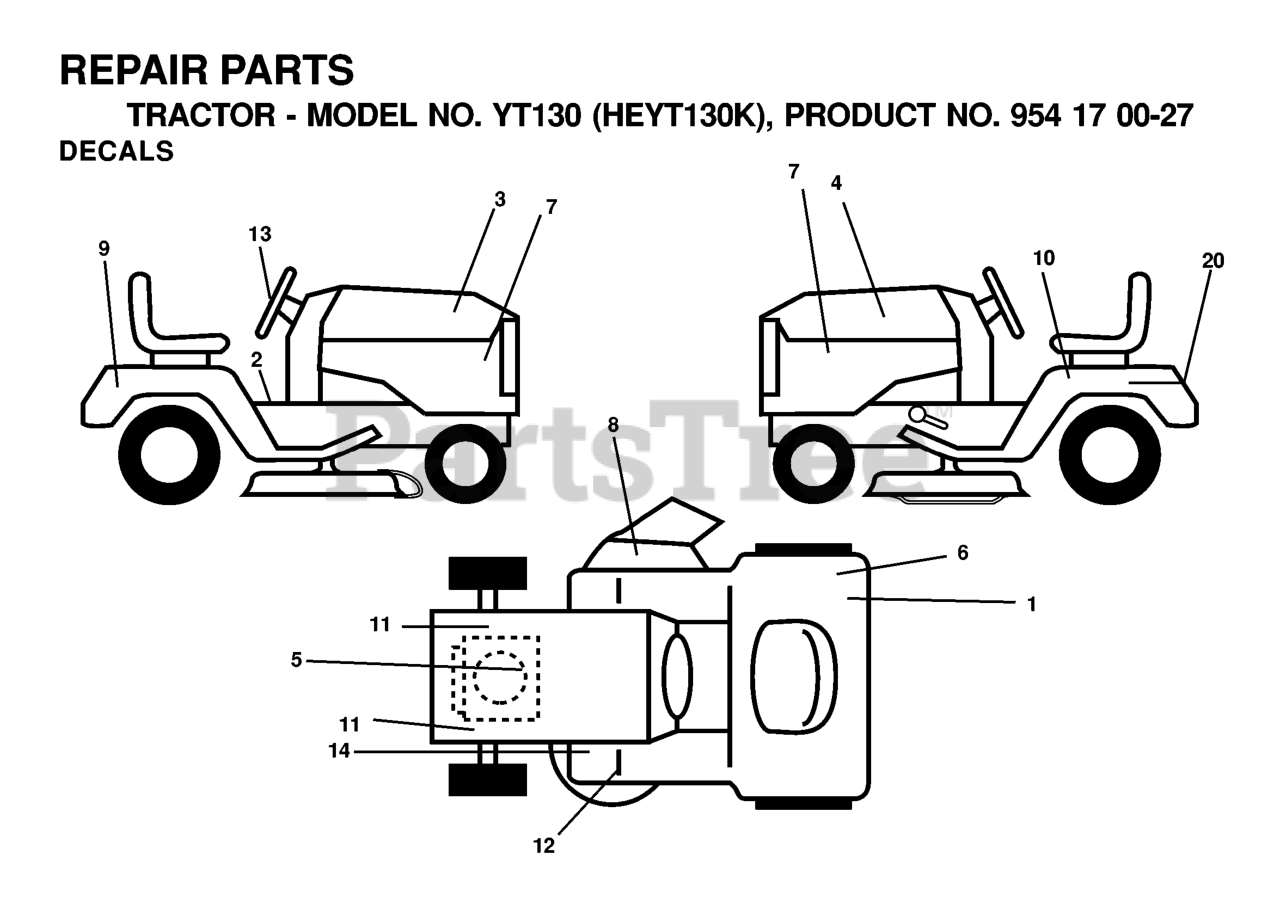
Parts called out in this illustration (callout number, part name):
1	RING-RTNG-EXTERNAL .625X.042
2	Washer-Flat-Steels .630 x 1.005 x .062
3	RIGHT MOUNT ARM WELDMENT
4	PIN CLEVIS .25 X 1.75
5	Bolt-Round Head Square Neck .31-18 x .50 Grade 5 (580 R, 580 RS, 580 RSE, 580 BBC, 600 C)
6	Nut-Locking-Flanged .31-18 (580 R, 580 RS, 580 RSE, 580 BBC, 600 C)
7	Fitting-Lube .25-28 x .256 (580 RSW, 600 C)
8	WHEEL YOKE WELDMENT
9	PIN-HAIR-EXT.
11	CLEVIS PIN
12	KICKOUT RING
13	WHEEL/7" X 1.75 EQUAL OFFSET
